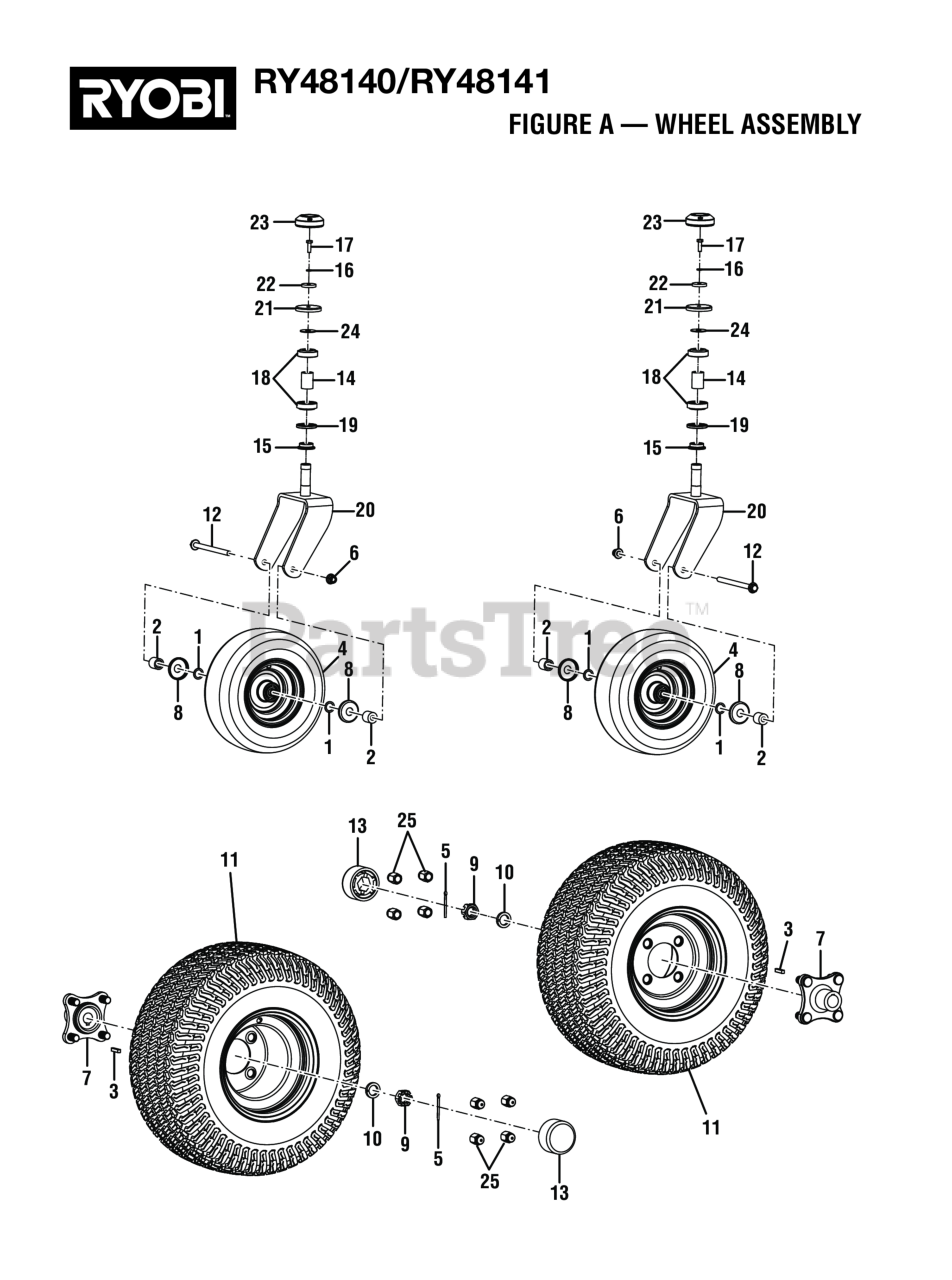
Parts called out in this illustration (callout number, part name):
1	Washer (OD28 x ID20.5 x 2t)
2	Caster Wheel Spacer
3	Key (6 mm x 6 mm x 30 mm)
4	Caster Wheel
5	Drive Shaft Cotter Pin
6	Flange Nut (M12)
7	Wheel Hub
8	Front Wheel Bearing Cover
9	Castle Nut (M20)
10	Lock Spring Washer (20.6 x 30.6 x 4.8t)
11	Rear Wheel Assembly
12	Flange Bolt (M12 x 170 mm, Hex Hd.)
13	Wheel Hub Cover
14	Bearing Assembly Spacer
15	Bearing Assembly Base
16	Lock Washer (OD9.8 x ID8.5 x 5t)
17	Bolt (M8 x 25 mm)
18	Roller Bearing (ID 25 mm x OD 52 mm)
19	Rubber Seal
20	Caster Fork
21	Bearing Assembly Cap
22	Fender Washer (OD37 x ID8.4 x 6t)
23	Caster Fork Cover
24	Fender Washer (OD40 x ID12.5 x 2t)
25	Acorn Nut (M14)
